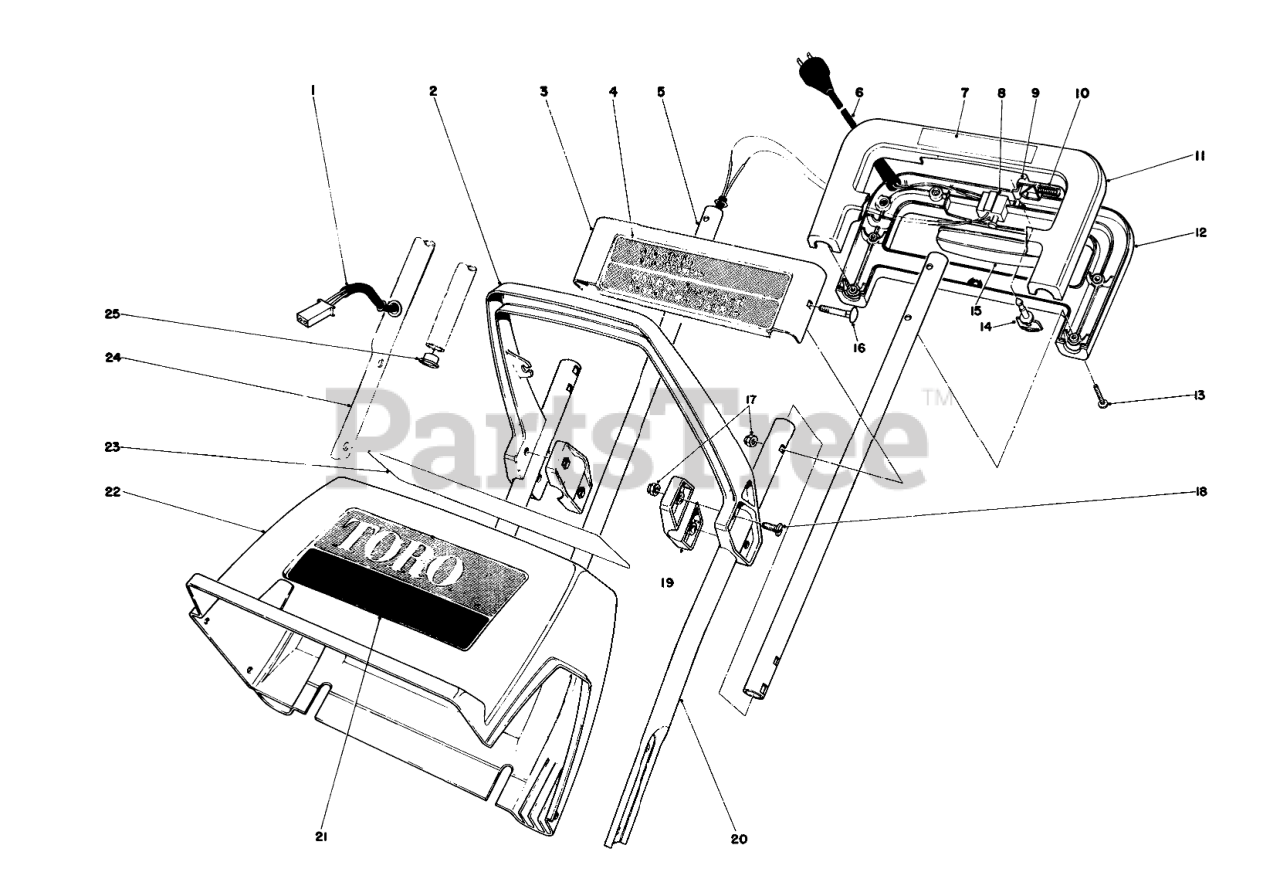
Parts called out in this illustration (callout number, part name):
1	Wire Harness
2	Middle Handle
3	Escutcheon Plate
4	Decal-Electric
5	Upper Tube
6	Cord Supply
7	Decal-Handle
8	SWITCH-STARTER
9	LOCKOUT, 1200
10	COMP SPRING
11	UPPER CONTRL HANDL HID
12	LOWR CONTRL HANDL HID
13	Screw
15	SWITCH BAR, 1200 PC
16	Bolt-Carriage
17	NUT-LOCK, NI
19	Clamp-Middle Handle
20	Handle-Lower L.H.
21	Decal-Toro S-120
22	Shroud S-120
23	Decal-U.L
24	Handle Lower R.H.
25	Snap Bushing
